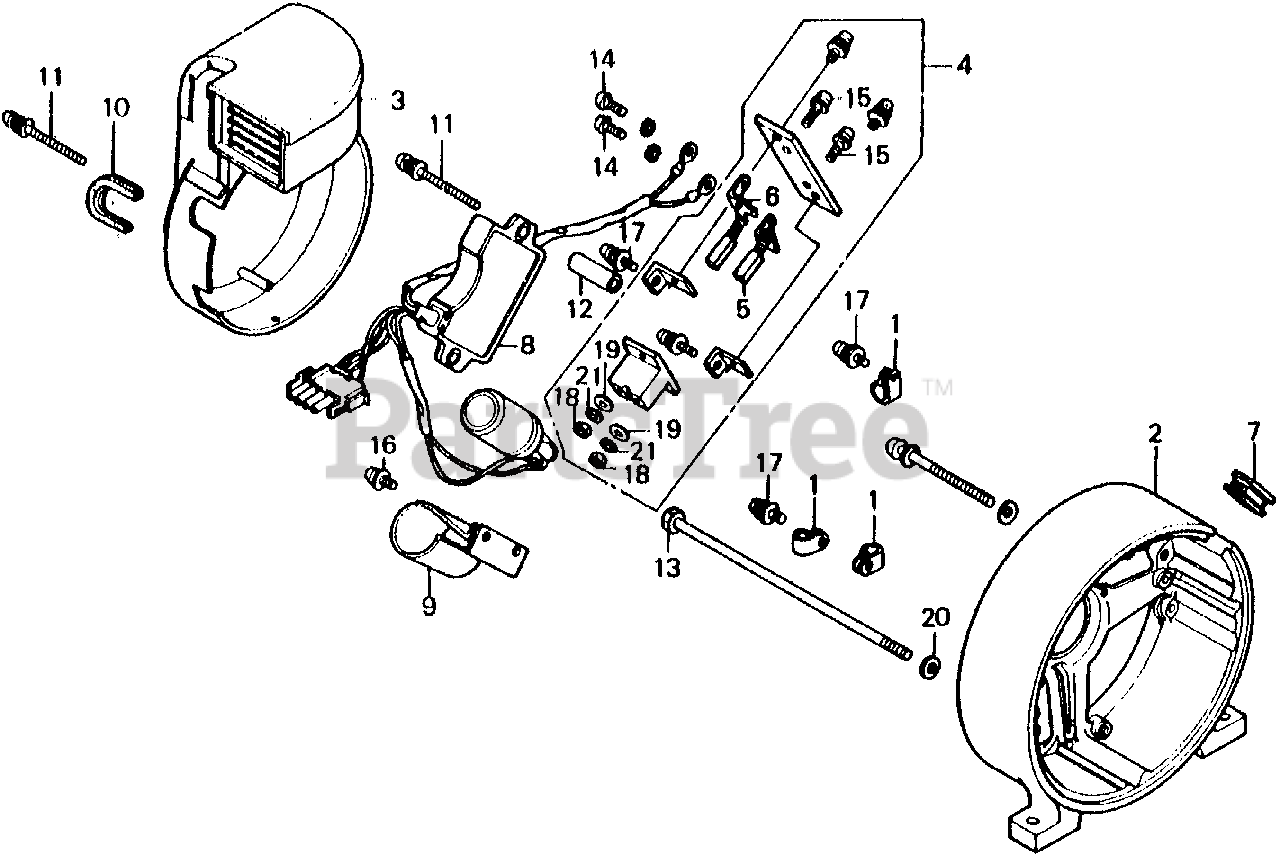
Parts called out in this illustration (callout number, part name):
1	CLAMP A, CABLE
2	HOUSING, RR. *NH31* (MCKINLEY WHITE)
3	COVER, GENERATOR END *NH116M* (URBAN SILVER METALLIC)
4	HOLDER ASSY., BRUSH
7	BUSH, RUBBER
8	REGULATOR ASSY., AUTOMATIC VOLTAGE (NOT AVAILABLE)
9	HOLDER, CONDENSER (NOT AVAILABLE)
11	SCREW-WASHER (5X55)
12	COLLAR (6.8X40)
13	BOLT, HEX. (6X190) (SOURCE: VINTAGE PARTS INC.)
14	SCREW, PAN (4X8)
15	SCREW-WASHER (4X16)
16	SCREW-WASHER (5X12)
17	SCREW-WASHER (5X14)
18	NUT, HEX. (4MM)
19	WASHER, PLAIN (4MM)
20	WASHER, PLAIN (6MM)
21	WASHER, SPRING (4MM)
